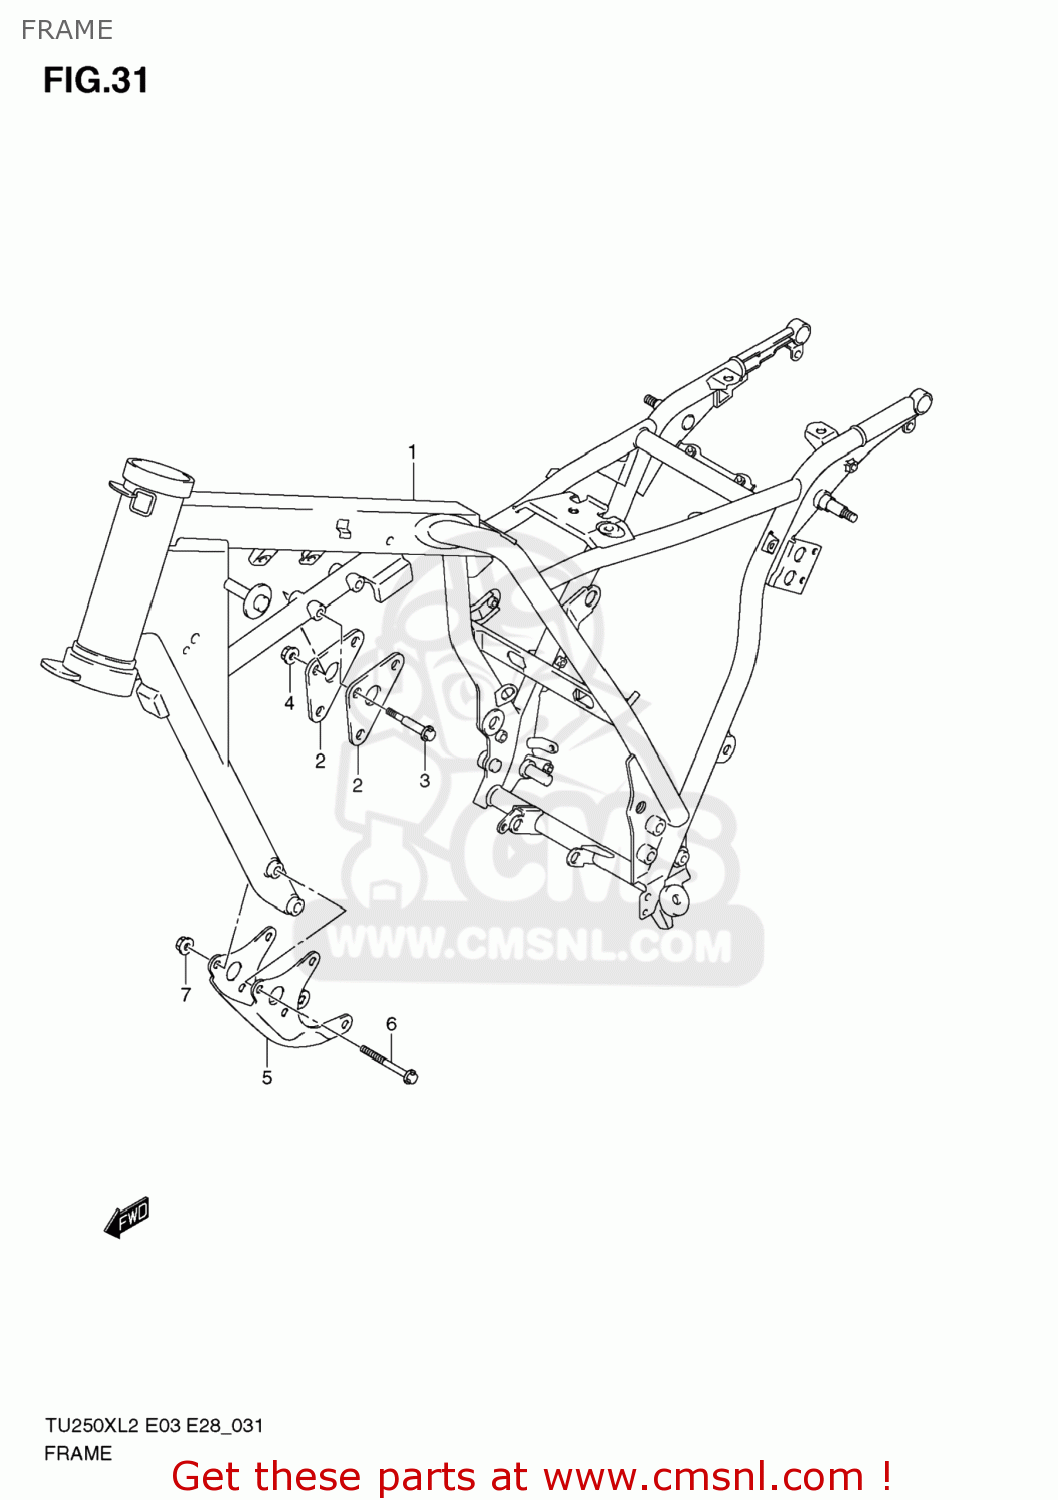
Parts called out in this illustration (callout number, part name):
1	FRAME(BLACK)
2	PLATE,ENG MTG UPR
3	BOLT(8X50)
4	NUT
5	PLATE,ENGINE MOUNT LWR
6	BOLT(8X67)
7	NUT
